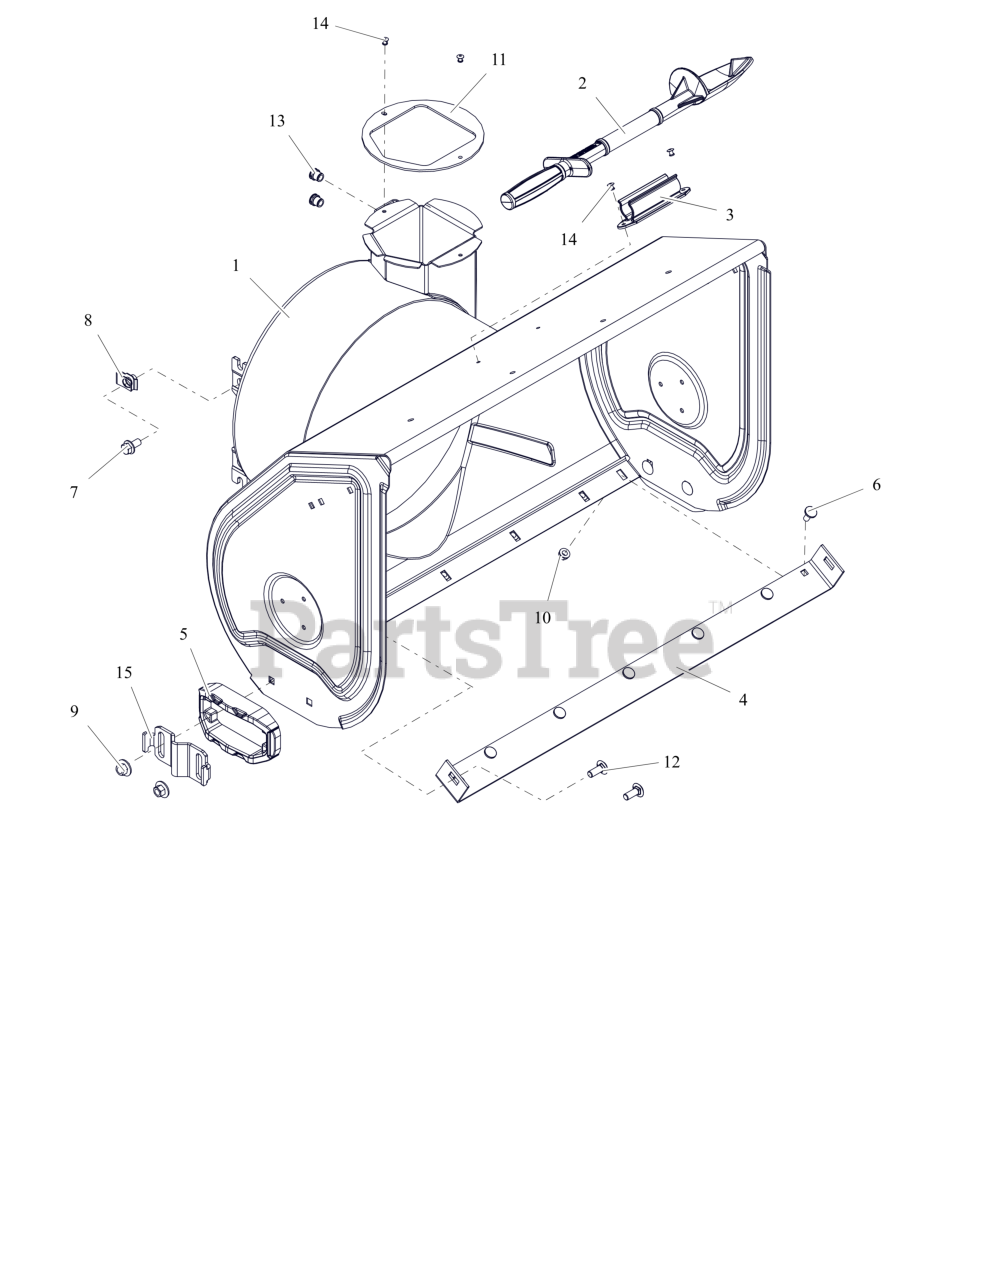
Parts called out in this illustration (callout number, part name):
1	HOUSING, BLOWER W/DECAL 30"
2	DEVICE, SNOW CLEAN OUT
3	MOUNT, SNOW CLEAN OUT
4	BLADE, SCRAPER-30"
5	SHOE, SKID - WEAR
6	BOLT, MODIFIED HEAD CARRIAGE
8	NUT-RTNR .375-16X.37
9	NUT- CON-LN .375-16 ZC120
10	NUT-LK-TOP-FLG .312-18 GF ZCC
11	BAFFLE, DISCHARGE NECK
12	BLT,RHSSN .38-16X1.00 G5 ZCC
13	NUT,THD,INSERT .38-16 ZC120
14	RVT, POP .1875 ZCC
15	SHOE, SKID - INSERT (BLACK)
